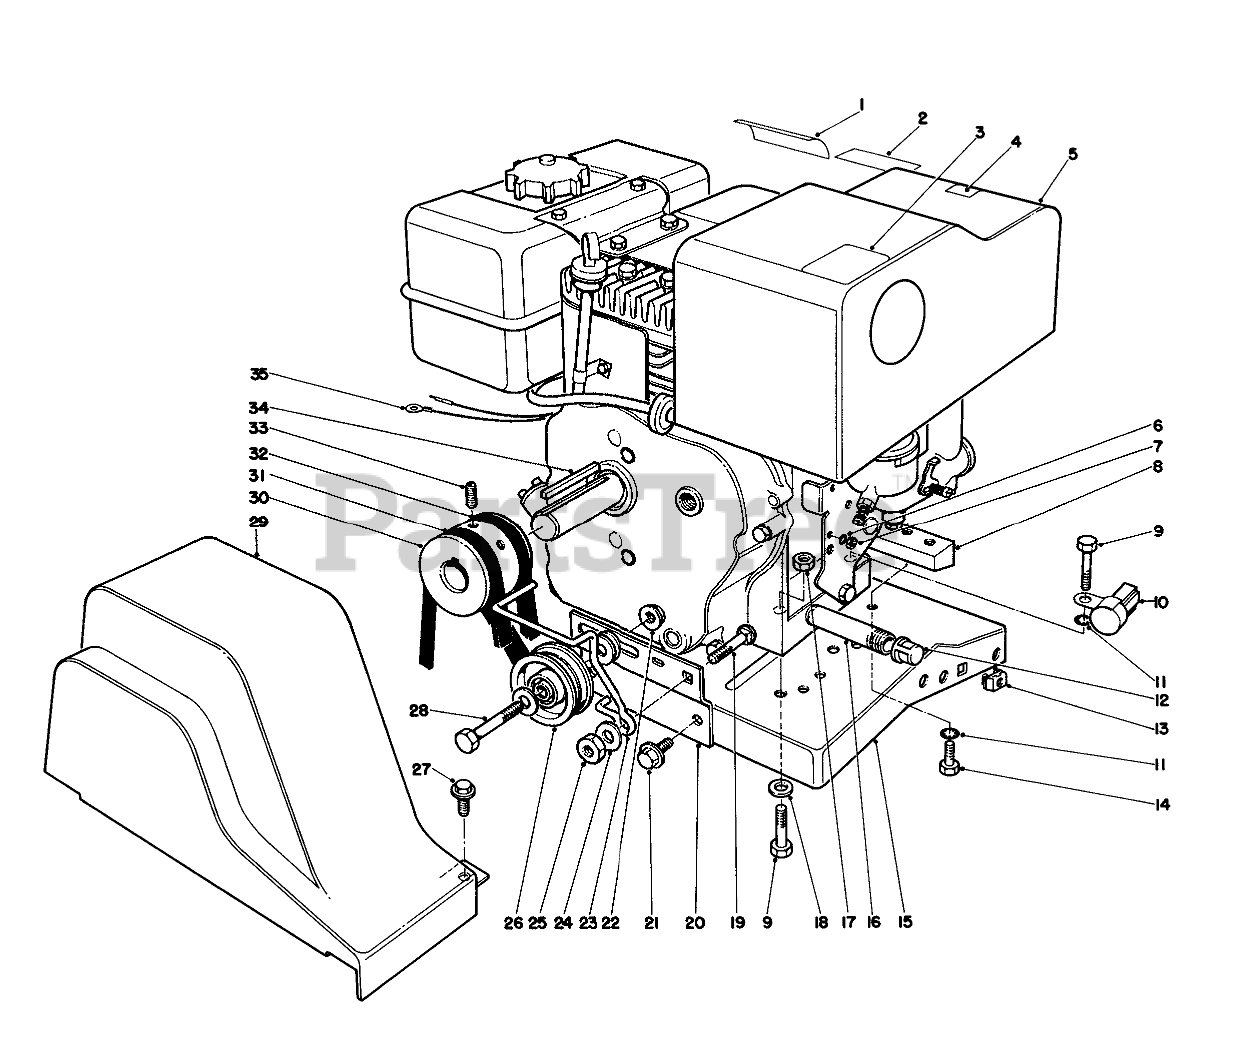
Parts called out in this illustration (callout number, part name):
1	HAZARDS CAUTION DECAL
2	Decal-Syncro Balance
3	Decal
4	Decal-Primer
5	Engine
6	WASHER-LOCK/INT
7	NUT-LOCK
8	Block Engine Mounting
9	SCREW-HH
10	INTERLOCK MODULE
11	WASHER-LOCK, INTERNAL
12	CAP-PIPE
13	RETAINER NUT
14	SCREW-HH
15	Engine Base
16	NIPPLE-PIPE
17	NUT-LOCK, NI
18	WASHER-PLAIN
19	SCREW-CARR
20	BELT IDLER BRKT
21	SCREW-HWHTF
22	NUT-HHF, WHIZ
23	BELT GUIDE
24	WASHER-FLAT
25	NUT-LOCK, NI
26	PULLEY B
27	SCREW-HWH
28	SCREW-HH
29	BELT GUARD
30	ENGINE PULLEY
31	V-BELT
32	V-BELT
33	Screw-Set
